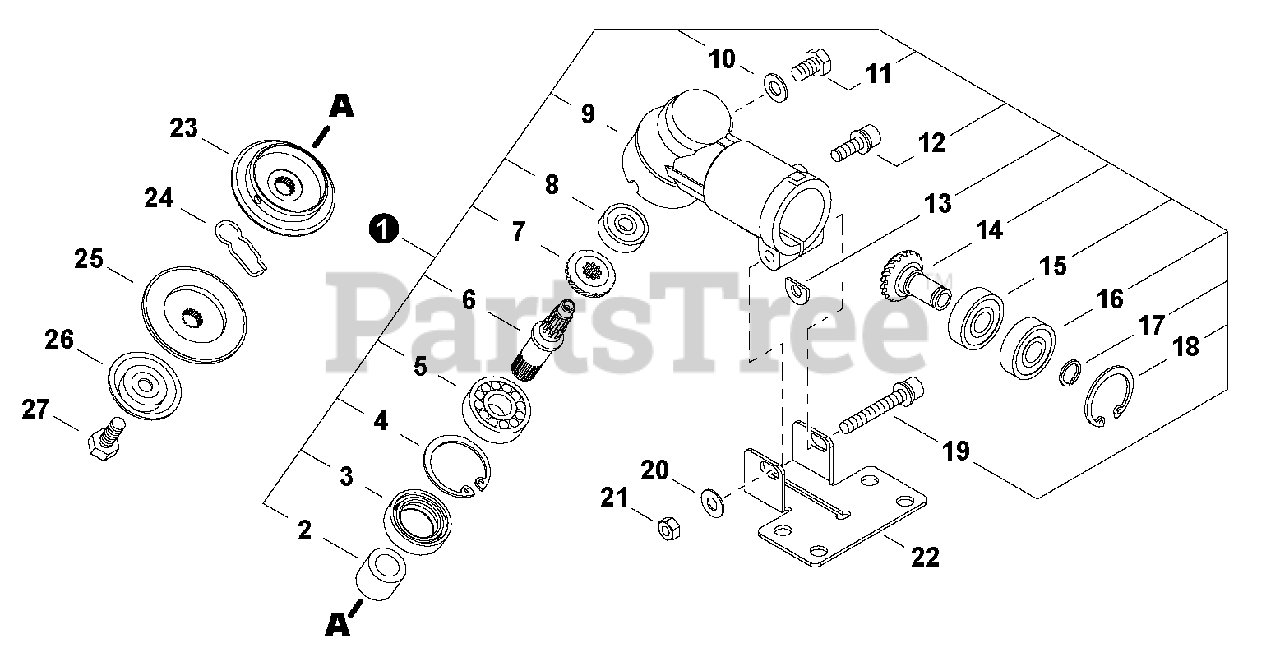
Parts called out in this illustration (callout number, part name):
1	Gear Case Assy
3	Seal, Oil
4	Ring, Snap dia.32
5	Bearing, Ball 6201
6	Shaft, Gear
7	Gear, Bevel
8	Bearing, Ball
9	Case, Gear
11	Bolt M6x10
12	Bolt M5x16
13	D-Washer
14	Gear, Pinion
15	Bearing, Ball 6901
16	Bearing, Ball 6901zz
17	Ring, Snap dia.12
18	Ring, Snap dia.24
19	Bolt M6x40
20	Washer 6
21	Nut, Hex M6
22	Plate, Shield Mounting
23	Holder (A)
24	Clip, Safety
25	Holder (B)
26	Guard, Bolt
